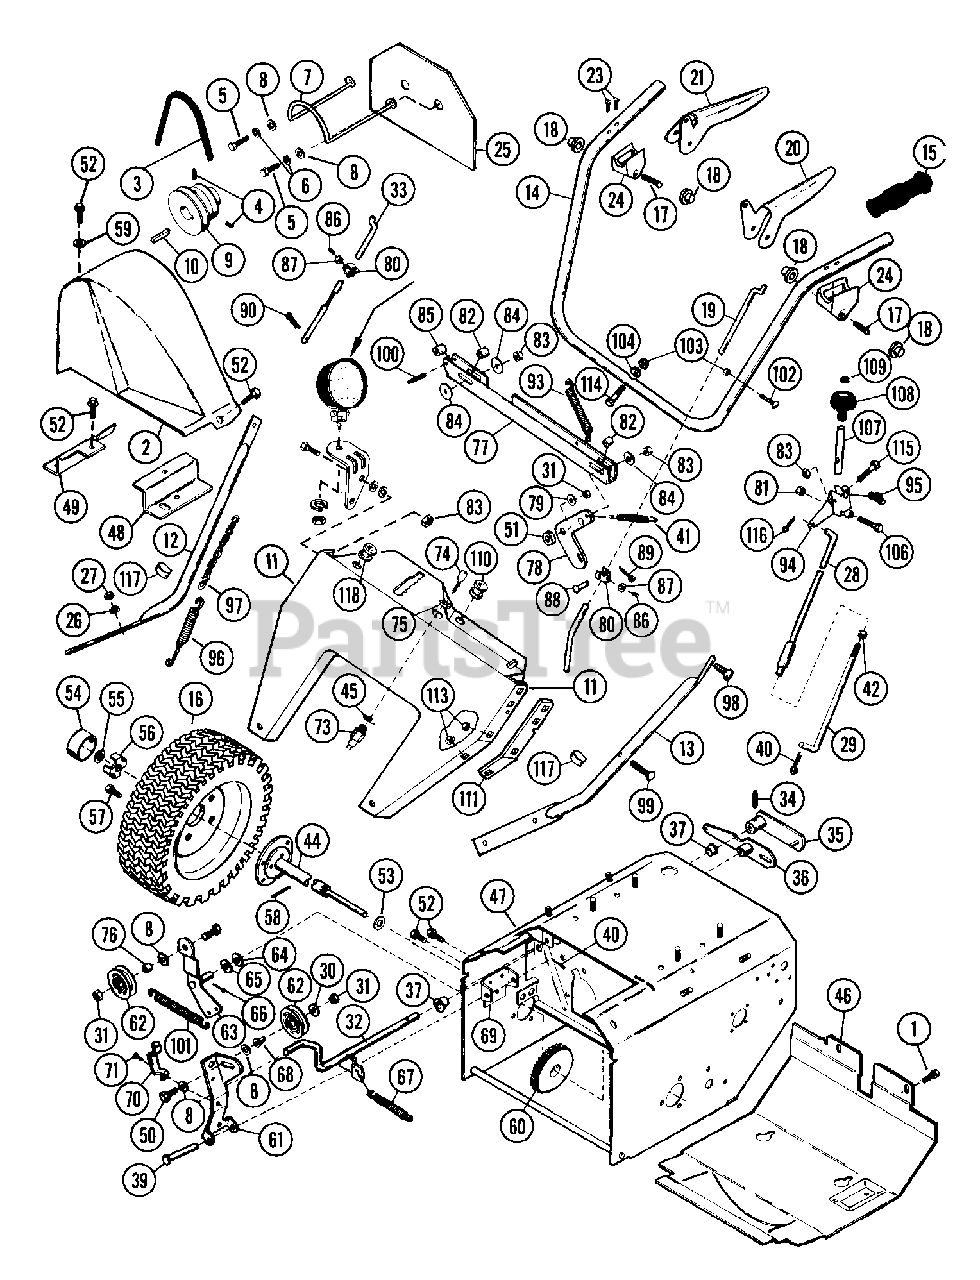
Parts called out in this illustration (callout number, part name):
1	BLT-SERHFWH .31-18X.50 PL
2	BELT COVER
3	V-BELT, 3L-RAW EDGE
4	SCR-SET .32-18X.38 SKHCUPNL OH
5	BLT-HEX .31-24X.75 PL GR5
6	WSHR-LK-EXT .313X.030 PL
7	BELT FINGER
8	WSHR-FL-STL .38X.875X.083 PL
9	SHEAVE, ENGINE
10	KEY-STR .25X1.75X.25
11	UPPER HANDLEBAR PANEL
12	LOWER HANDLEBAR RH
13	LOWER HANDLEBAR LH
14	UPPER HANDLEBAR LW
15	GRIP
16	TERRA TIRE & WHEEL ASSEMBLY
16	TIRE 16X6.50-8 2 PLY
16	TUBE
16	WHL
16	WHEEL ASSEMBLY
16	TIRE
18	PUSH NUT, .25
19	CLUTCH ROD
20	TRACTION CLUTCH HANDLE WITH DE
21	ATTACHMENT CLUTCH HANDLE
23	SCR-TAP 12-14X1.50 CROVH PL BT
24	HANDLE PIVOT
25	PLATE
26	WSHR-LK .375X.115 HVY PL
27	NUT-HEX .375-16
28	UPPER SHIFT ROD
29	LOWER SHIFT ROD
30	WSHR-FL-STL.312X.734X.065PL
31	NUT-LK .312-18 GR A PL
32	ACTIVATING SHAFT
33	ATTACH CLUTCH ROD
34	PIN-ROLL .156X.88
35	LEVER CLUTCH
37	BSHG-FLG.500X.625X.312X.750NY
39	PIN-CLEV .309X2.25
40	PIN-COTR .09X.75 PL
41	SG-TENS .062X.43X5.75 WLD 20
42	NUT-HEX .312-24 PL
44	R H AXLE
45	WSHR-LK-INT .625X.045 PL
46	BOTTOM COVER
47	TRACTOR FRAME
47	FRAME
48	L.H. SUPPORT
49	R.H. SUPPORT
50	BLT-HEX .31-18X1.25 PL GR2
51	SPACER BUSHING .5 X .32 X .163
52	BLT-SERHFWH .25-20X.50 PL
53	WSHR-FL-STL .880X1.380X.062
54	HUB CAP
55	PUSHNUT
56	SPINDLE CUP
57	BLT-WHL .50-20X.75 GR5 PL
58	PIN-ROLL .188X1.50
59	WSHR-FL-STL .268X.562X.046 PL
60	DIFFERENTIAL ASSEMBLY
61	ARM, IDLER
62	IDLER
63	IDLER ARM
64	WSHR-FL-STL .382X.812X.023 PL
65	WAVE WASHER .406X.750X.063FH
66	PIN-COTR .12X1.0 PL
67	SG-TENS .047X.44X3.37 WLD 1.47
68	SPCR, BRG .315X.50X.688X.281
69	BRACKET
70	RETURN CLIP
71	SCR-TAP 10-24X.375 HWH PL TR
73	SWITCH & KEY SET ASSEMBLY
74	KEYS
75	NUT .625-32 ALUM
76	SPACER .50 X .32 X .42
78	BELLCRANK
79	WSHR-FL-STL .328X.875X.062 PL
81	NUT-LK .312-18 GR A PL
82	BSHG-SLV .250X.375X.640
83	NUT-LK-CTR .250-20 PL
84	WSHR-FL-STL .281X1.250X.048PL
85	BSHG-SLV .188X.500X.480
86	SCR-SET .25-20X.75 SKHCUP OH
87	NUT-HEX JAM .25-20 YWZC
88	CLEVIS PIN
89	PIN-HAIR INT .06X.18X.77
90	PIN-COTR .12X.50 PL
93	SG-TENS .035X.45X2.75 WLD 3.5
95	SG-TENS .055X.33X1.31 WLD 7
96	SG-TENS .091X.56X6.12 WLD 40
97	CLUTCH CHAIN
98	BLT-RDHDSQNK .31-18X.75 PL BL
99	BLT-RDHDSQNK .31-18X1.50 PL BL
100	PIN-ROLL .188X.88
101	SG-TENS .080X.73X3.06 WLD 20
102	BLT-RDHDSQNK .25-20X1.50 PL BL
103	NUT-LK-FLG .250-20 PL
104	WSHR-FL-STL .265X.500X.087 PL
106	BLT-HEX .31-18X2.50 PL GR2
107	ROD
109	RG-RTNG-EXT .500X.015
110	SNAP BUSHING
111	R H STIFFENER
111	L H STIFFENER
113	NUT-FLG. .312-18 PL
114	BLT-HEX .25-20X1.50 PL GR5
115	BLT-HEX .25-20X1.00 GR2
116	PIN-COTR .12X.75 PL
118	SNAP BUSHING-.437
